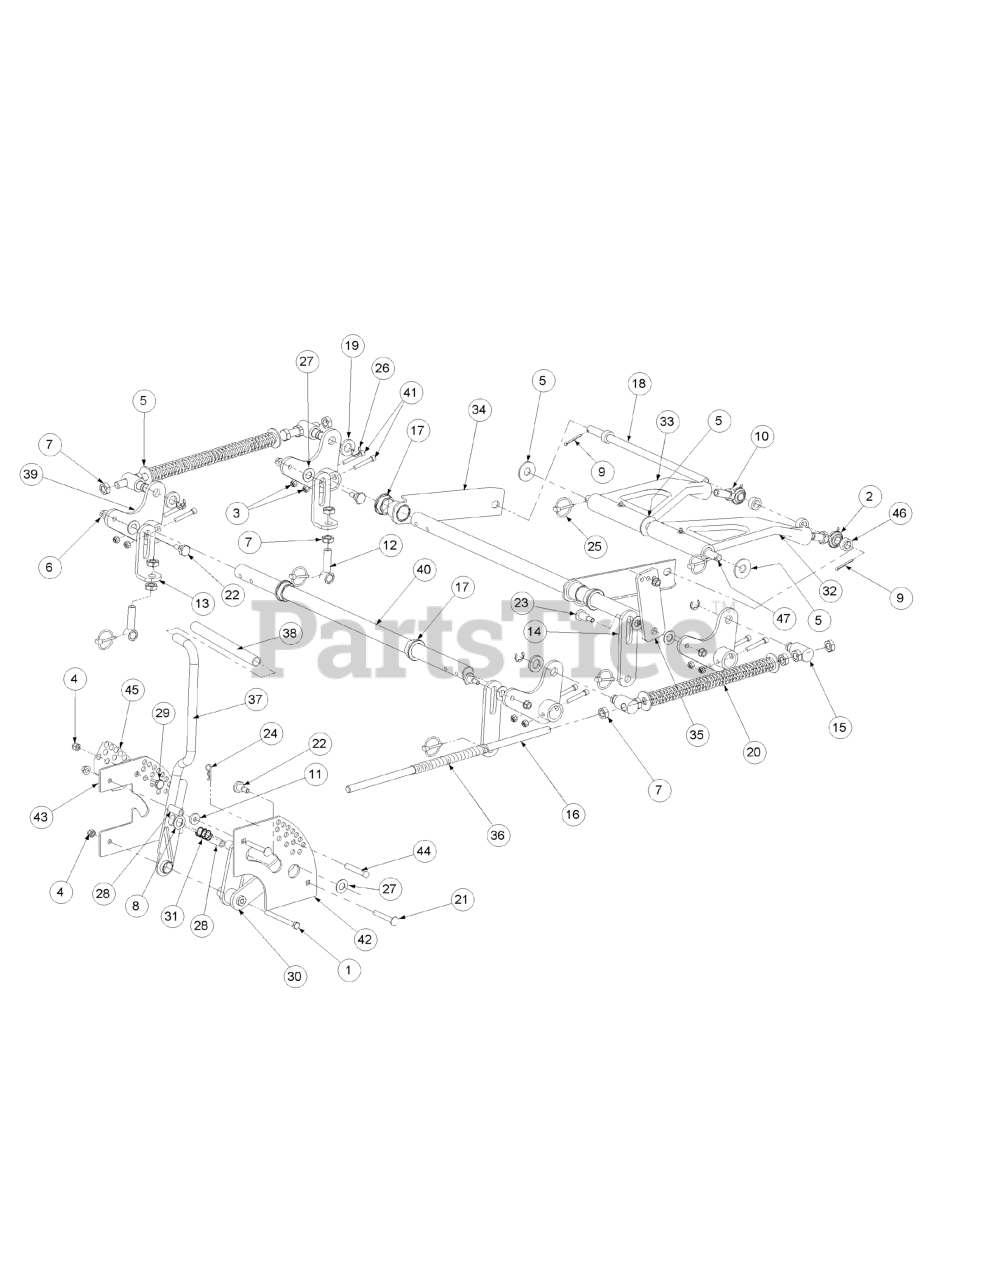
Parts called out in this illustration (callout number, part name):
1	Hex Cap Screw, 3/8-16, 3.75
2	Rod End, Male
3	Nut, 5/16-18, Nylock
4	Nylock Insert Lock Nut, 3/8-16
5	Flat Washer, 5/8
6	Hex Nut, Flange Lock, 3/8-16
7	Jam Nut, 5/8-11
8	Flat Washer, .06, .776, 1.25
9	Cotter Pin, 3/16 x 1-1
10	Jam Nut, 5/8-18
11	Idler Washer
12	Eye Bolt, 5/8ID
13	Eye Bolt Mount Link, 5/8 ID
14	Deck Link
15	Ferule Lift
16	Lift Connector Rod
17	Hex Flange Bearing, 1.25 ID
18	Front Lift Link, Rod Mount
19	Spacer, .812 ID x .268 Lg.
20	Lift Compression Spring
21	Carriage Bolt, 3/8-16, 2.75
22	Shoulder Screw, 0.625 OD x .437 Lg.
23	Shoulder Screw, 0.625 OD x .830 Lg.
24	Cotter Pin, .148 x 3.00
25	Linch Pin, 3/16 Dia.
26	E Clip, 3/4 Dia.
27	Nylon Flat Washer, 5/8
28	Spacer, .39 ID x .63 OD x 1.442
29	Shoulder Screw, .50 OD x 0.27
30	Lift Pivot Assembly
31	Lift Handle Spring
32	Bearing Lift Brace Assembly, Right Hand
33	Bearing Lift Brace Assembly, Left Hand
34	Front Frame Strut Assembly
35	Lift Link Adjustment
36	Hose, 5/8 ID 13/16 OD, 8" LG
37	Lift Handle Assembly
38	Lift Handle Grip
39	Bellecrank Weldment Assembly
40	Deck Lift Shaft
41	Socket Head CapScrew, 5/16-18 x 2
42	Outer Lift Index Plate
43	Inner Lift Index Plate
44	Clevis Pin, .438 Dia. x 2.625 Lg.
45	Decal Height Indicator
46	Spacer, .630 ID x 1.06 OD x .440
47	Lift Link Rod
